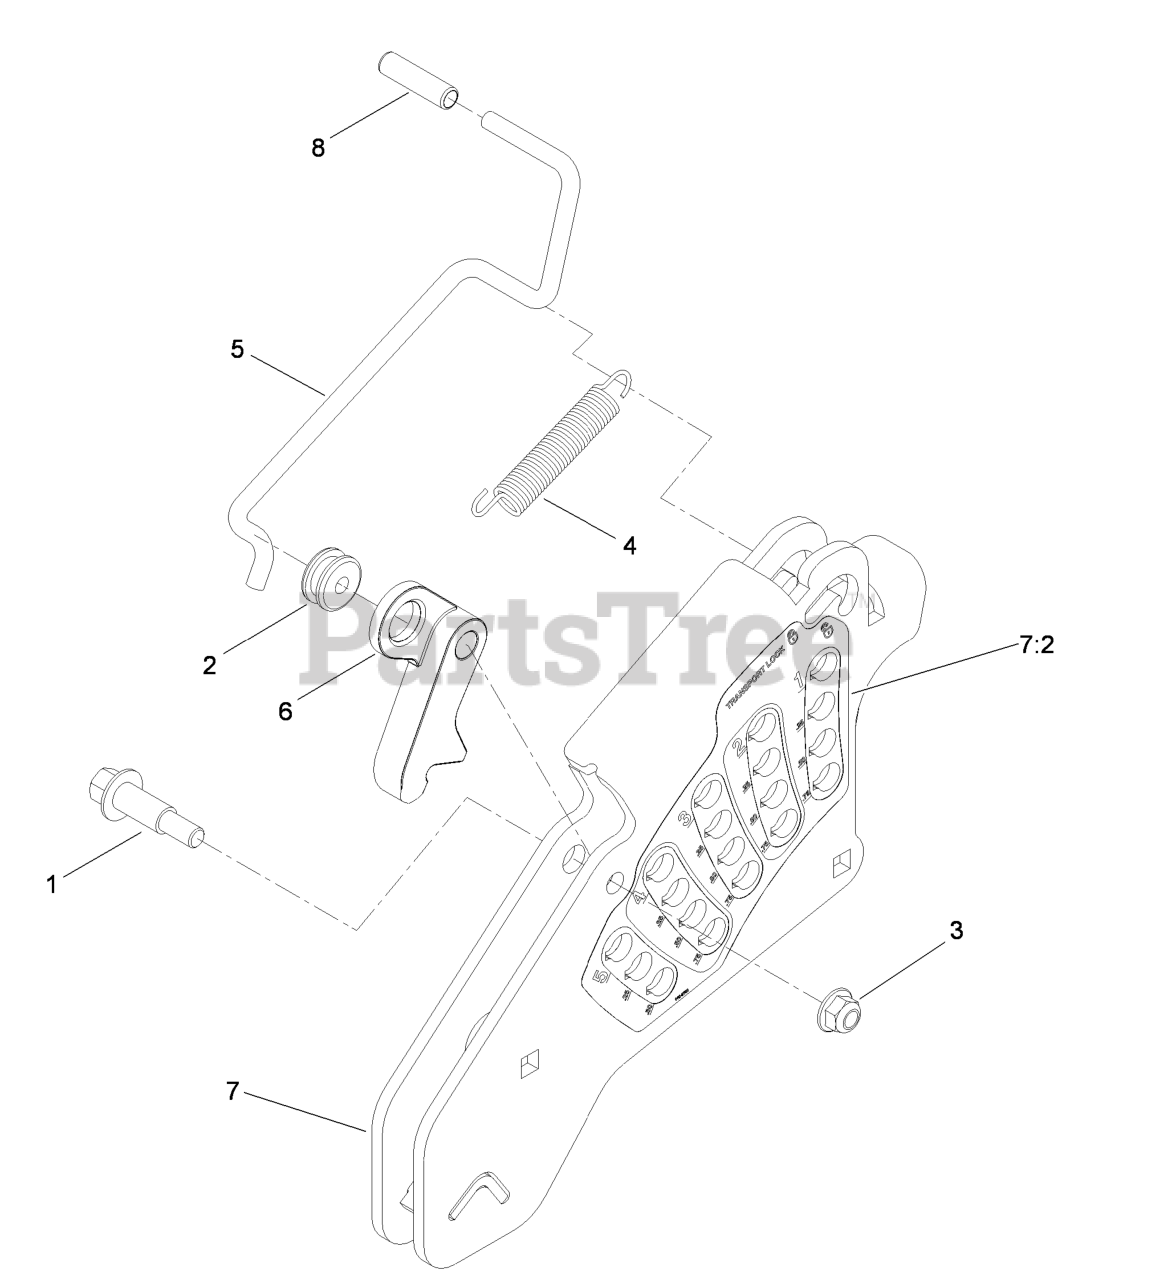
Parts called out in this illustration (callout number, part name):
1	BOLT-SHOULDER
2	GROMMET
3	NUT-HF, NI
4	SPRING-EXTENSION
5	ROD-LOCK, TRANSPORT
6	PAWL-TRANSPORT, HOC
7	HOC PLATE ASM
7:2	DECAL-HOC
8	GRIP-LEVER
